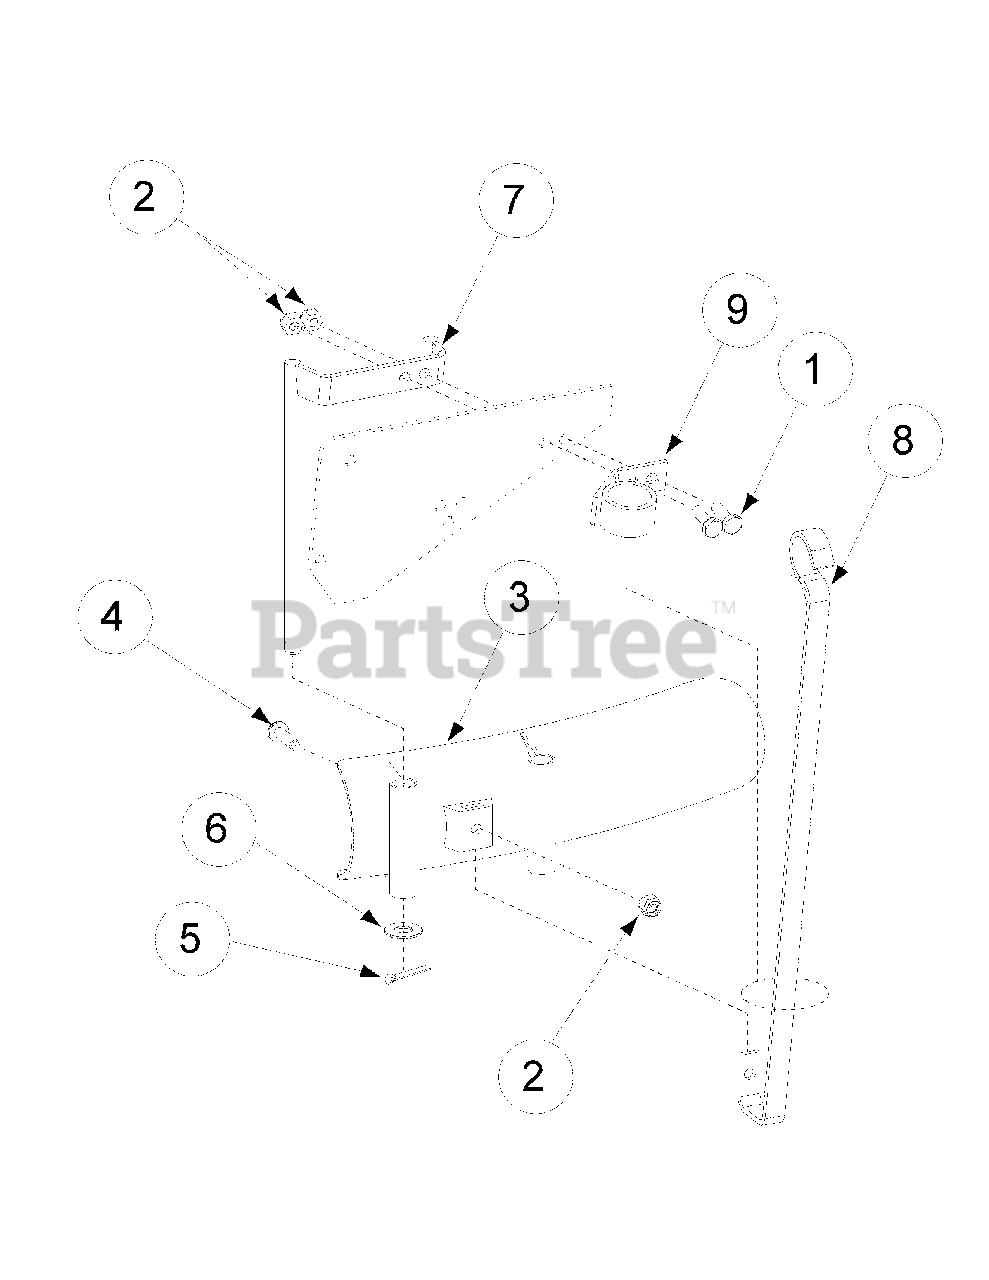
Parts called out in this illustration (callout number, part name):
1	Screw, 1/4-20 x .75
2	Lock Nut, 1/4-20
3	Deflector
4	Screw, 1/4-20 x 7/8
5	Cotter Pin
6	Flat Washer
7	Mounting Tube
9	Ring Support
